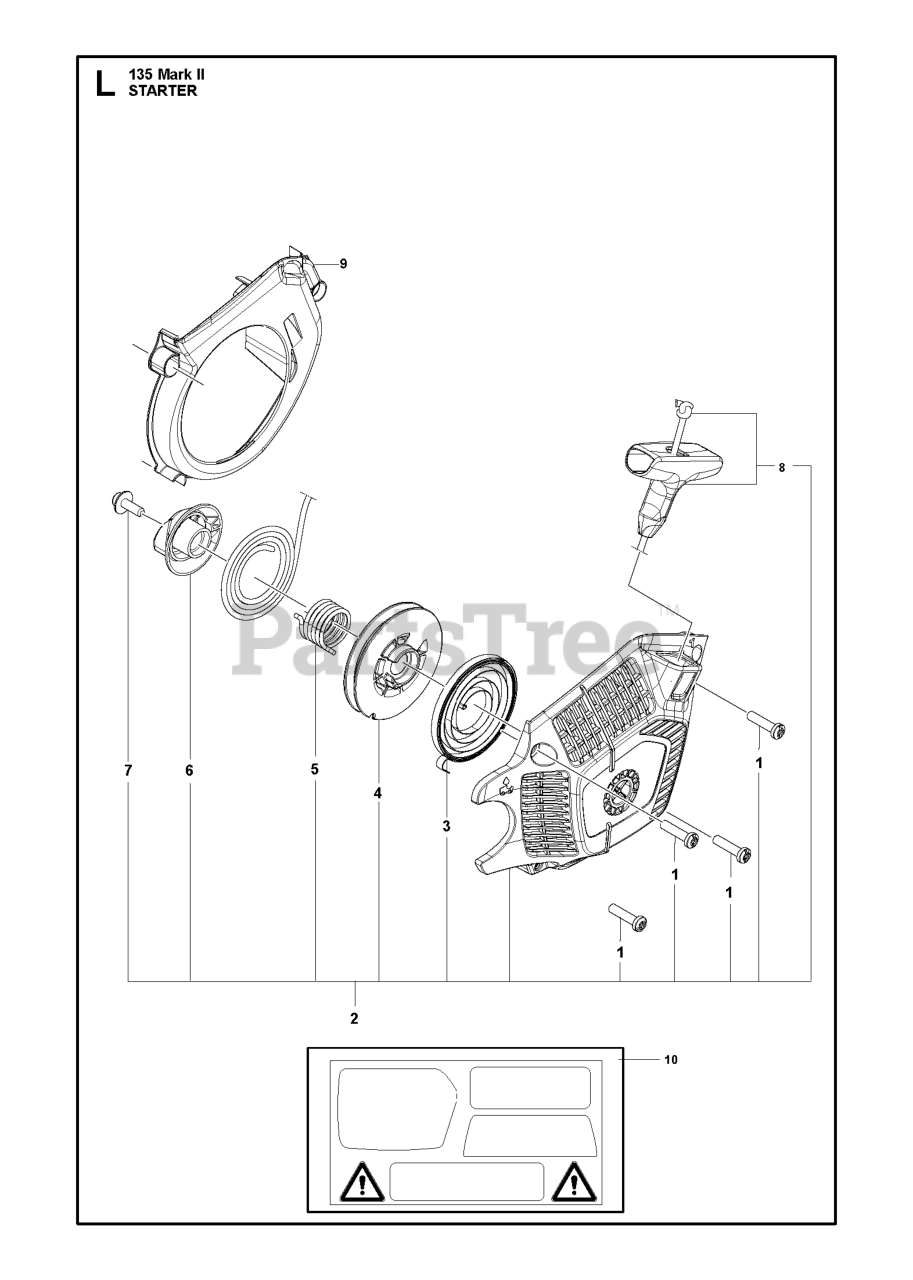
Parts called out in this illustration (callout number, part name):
1	SCREW M5.38-14X22.225MM
2	SERVICE KIT STARTER HOUSING 13
4	PULLEY STARTER - SAMWISE
5	SPRING STARTER ASSIST - SAMWIS
6	HUB STARTER- SAMWISE
8	STARTER ROPE W/HANDLE
9	BAFFLE 130 CHAINSAW
10	SERVICE KIT DECAL
